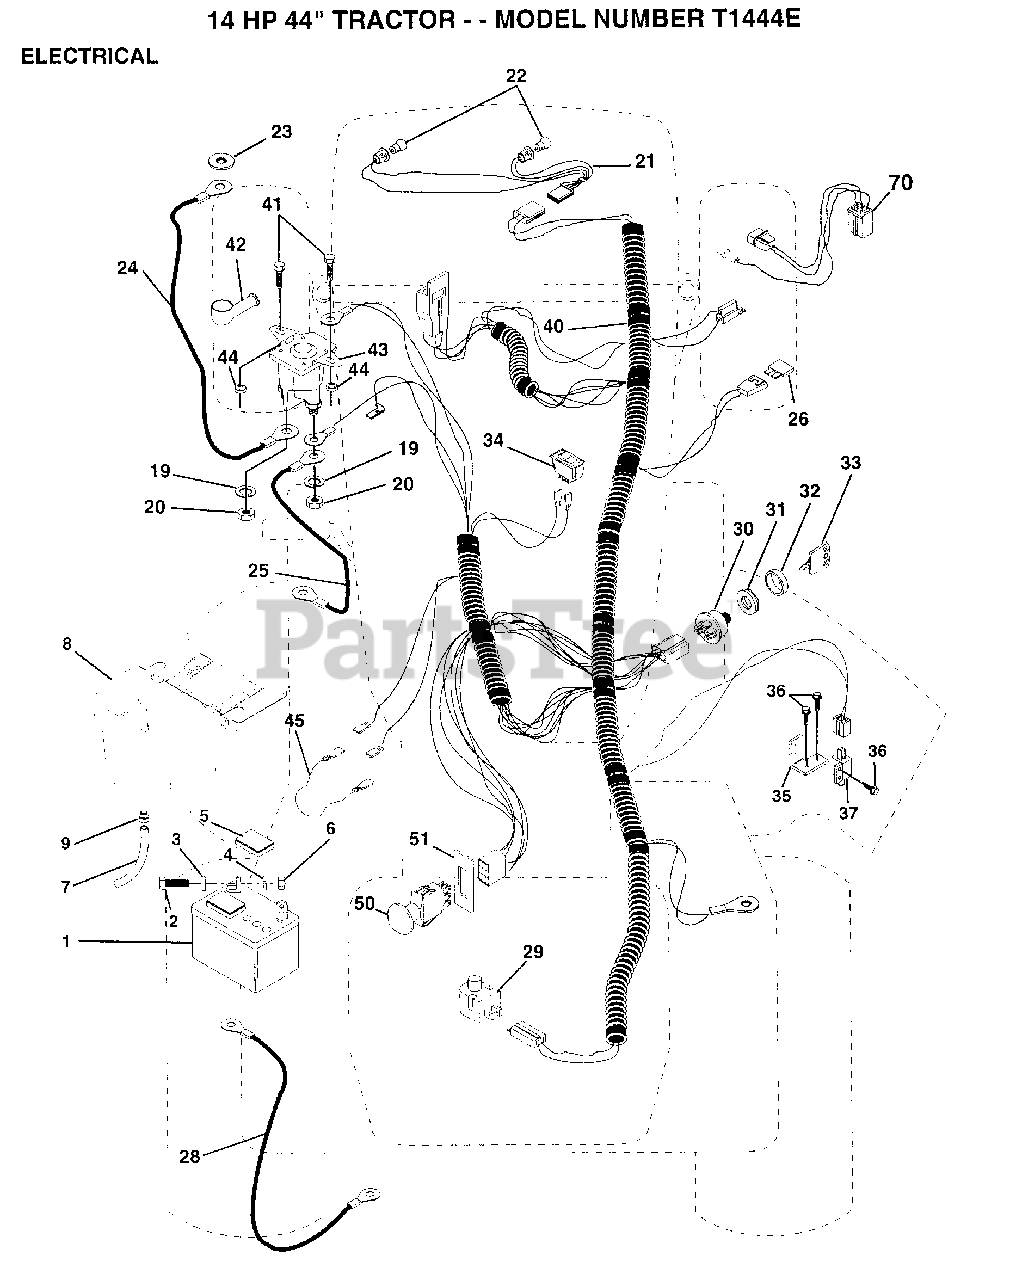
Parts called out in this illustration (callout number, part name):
2	BOLT LT
3	WASHER
4	LOCKWASHER
5	"CAP,BATTERY "
7	TUBE T
9	HOSE CLAMP T
20	NUT
21	"HARNESS,LIGHT SOC"
22	HEADLAMP BULB
23	LOCKWASHER
24	CABLE T
26	FUSE HYT
28	CABLE-BATTERY T
29	SWITCH SEAT
32	COVER KEY SWITCH
33	KEY MLD GEN DELTA
34	SWITCH LT
35	BRACKET LT
36	SCREW
37	SWITCH-INTER. GT
40	HARNESS IGN DASH
41	BOLT HXHD FIN
44	NUT
45	ADAPTER AMMETER
51	RING RETAIN PTO
70	HARNESS.ENG.B&S
